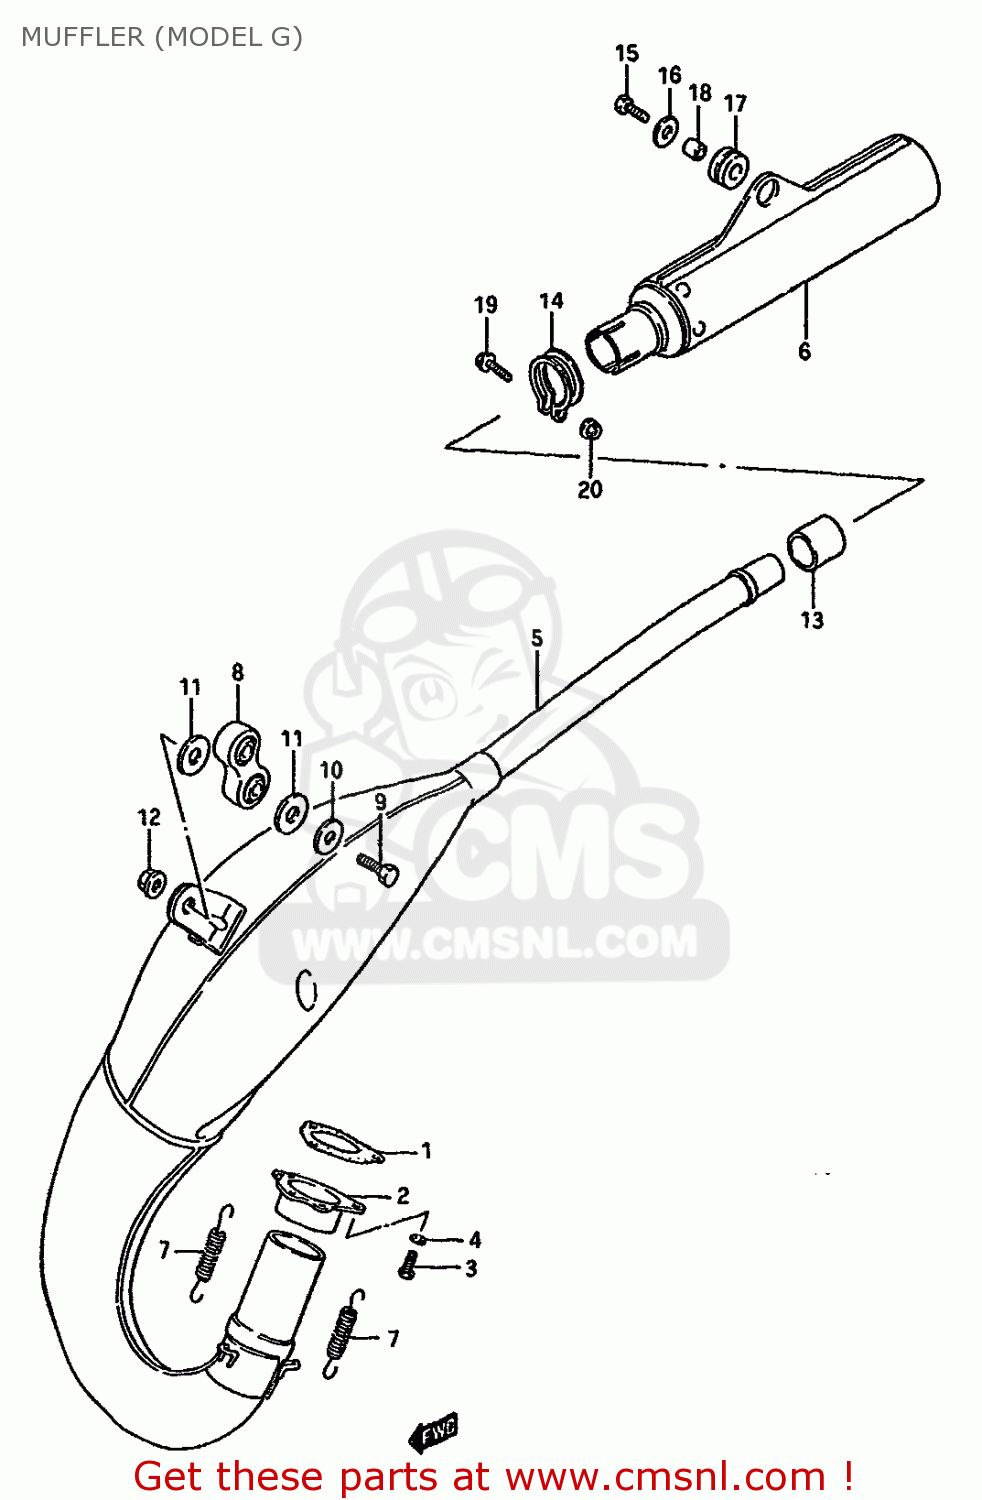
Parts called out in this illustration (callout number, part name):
1	GASKET,EXHAUST PIPE (MCA)
2	FLANGE COMP,EXHAUST PIPE
3	SCREW
4	WASHER,LOCK
5	MUFFLER,IST
6	MUFFLER,2ND
7	SPRING
8	DAMPER,MUFFLER
9	BOLT(8X32)
10	WASHER
11	WASHER(13X28X1.6)
12	NUT
13	GASKET,SECOND MUFFLER (NAS)
14	CLAMP,MUFFLER SECOND
15	BOLT 6X22
16	WASHER (6.5X24X1.6)
17	CUSHION
18	SPACER (6.4X9X10.5)
19	BOLT
20	NUT 6MM
